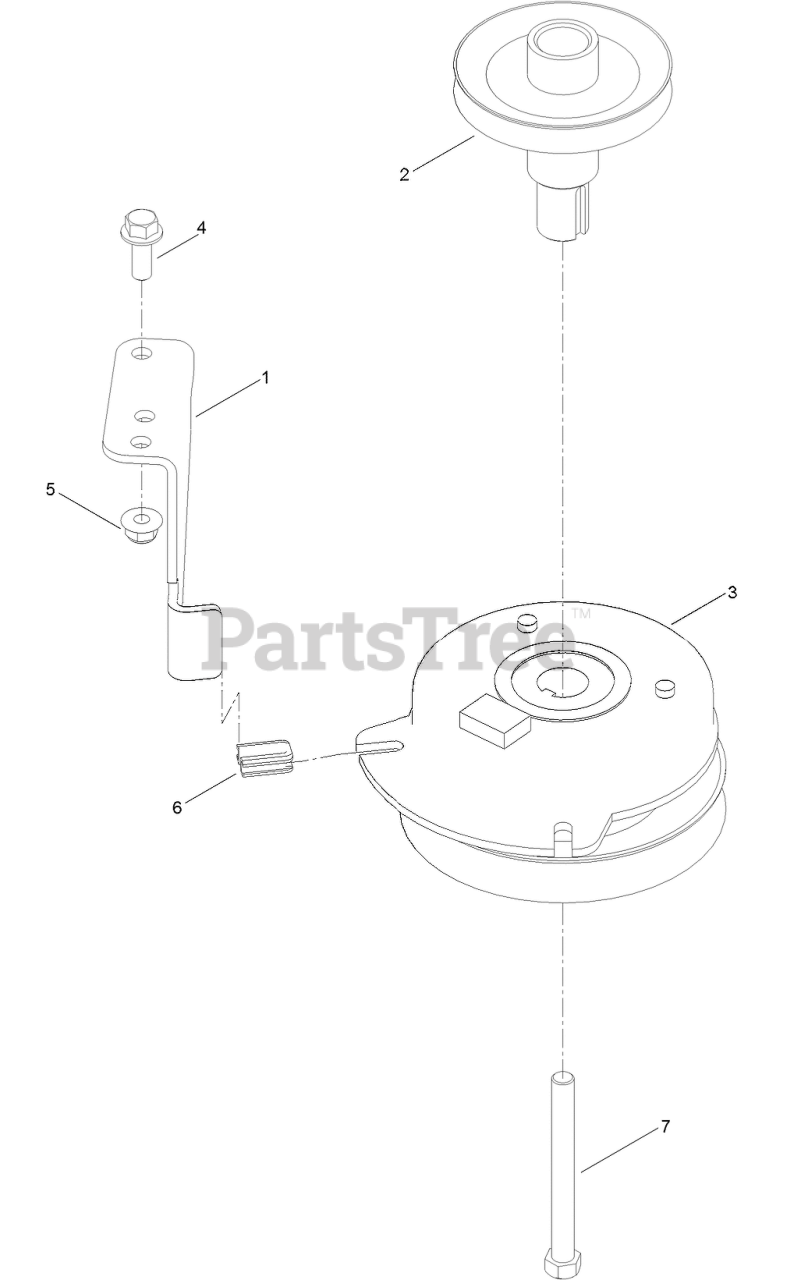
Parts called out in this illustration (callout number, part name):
1	STOP-CLUTCH (WIDE)
2	PULLEY-ENGINE
3	CLUTCH-PTO
4	SCREW-HHF
5	NUT-HF, NI
6	ISOLATOR-CLUTCH
7	SCREW-HH
